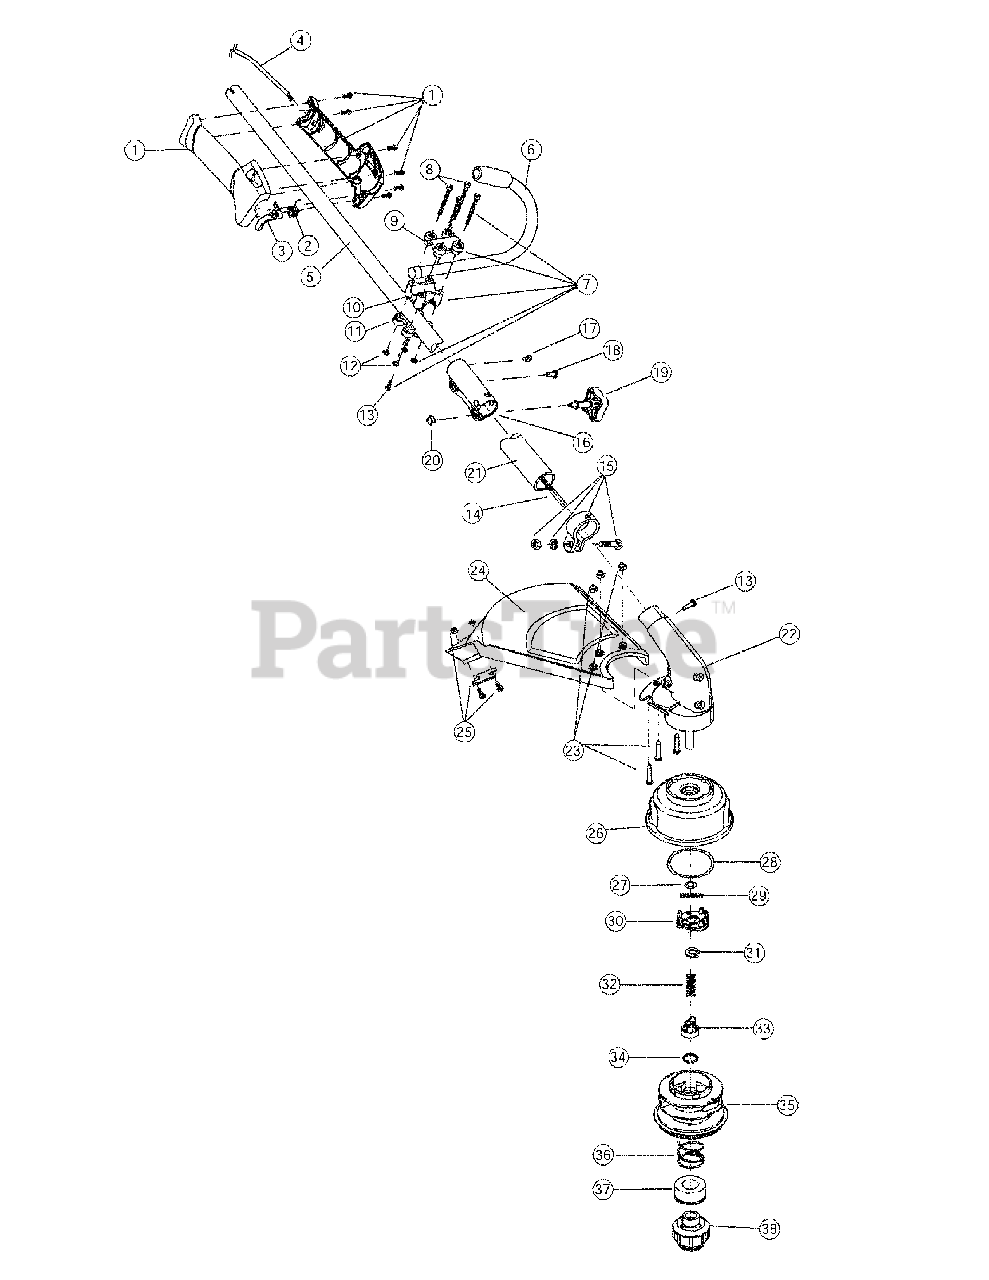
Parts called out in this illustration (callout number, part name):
1	Throttle Housing and Trigger Assembly
2	Throttle Trigger Spring
3	Throttle Trigger
4	Throttle Cable Assembly
5	Upper Drive Shaft Housing Assembly
6	J-Handle Assembly
7	Handle Bracket Assembly
9	Upper Handle Clamp
10	Middle Handle Clamp
11	Lower Handle Clamp
13	Anti-Rotation Screw
14	Lower Flexible Drive Shaft
15	Lower Clamp Assembly
16	Split Boom Coupler
19	Adjustment Knob
20	Knob Retaining Nut
21	Lower Drive Shaft Housing Assembly
22	Gearbox Assembly
23	Shield Mounting Hardware
24	Shield Assembly
25	Blade Assembly
26	Outer Spool Assembly
27	Retainer
28	Thrust Washer
29	Small Spring
30	Slider
33	Plunger
35	Inner Reel
36	Large Spring
37	Foam Seal & Washer
38	Bump Head Knob Assembly
